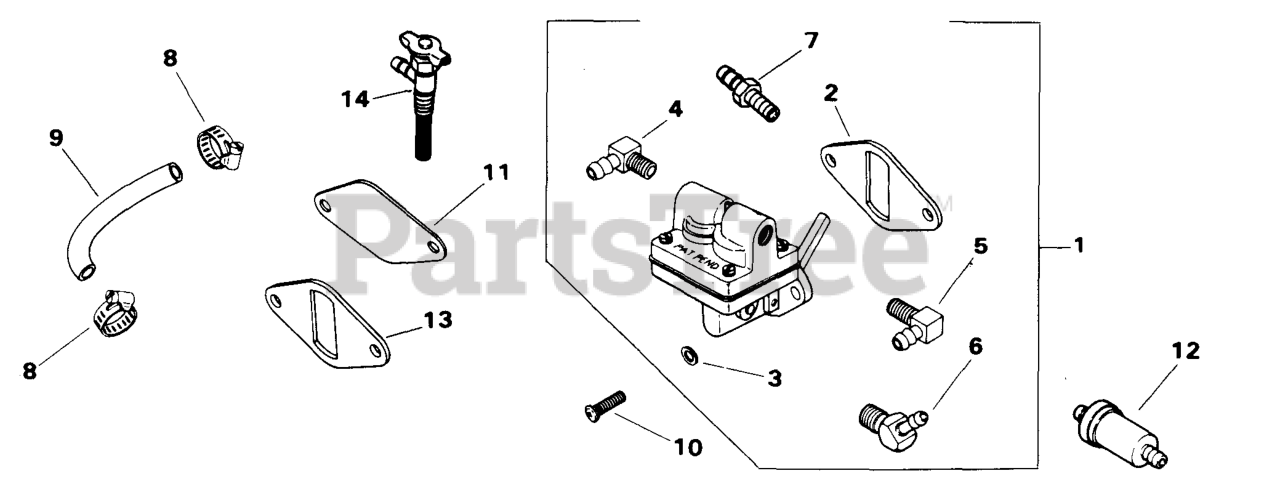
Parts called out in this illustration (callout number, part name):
1	Pump, Fuel Assembly (W/Threaded Fittings)
2	Gasket, Fuel Pump
3	Washer, Plain 1/4"
5	Connector, 90 Degree Hose
7	Connector, Straight
8	Clamp, Hose 1/2"
9	Line, Fuel 6-3/4"
10	Screw, Pozidriv T.H. 1/4-20x5/8"
